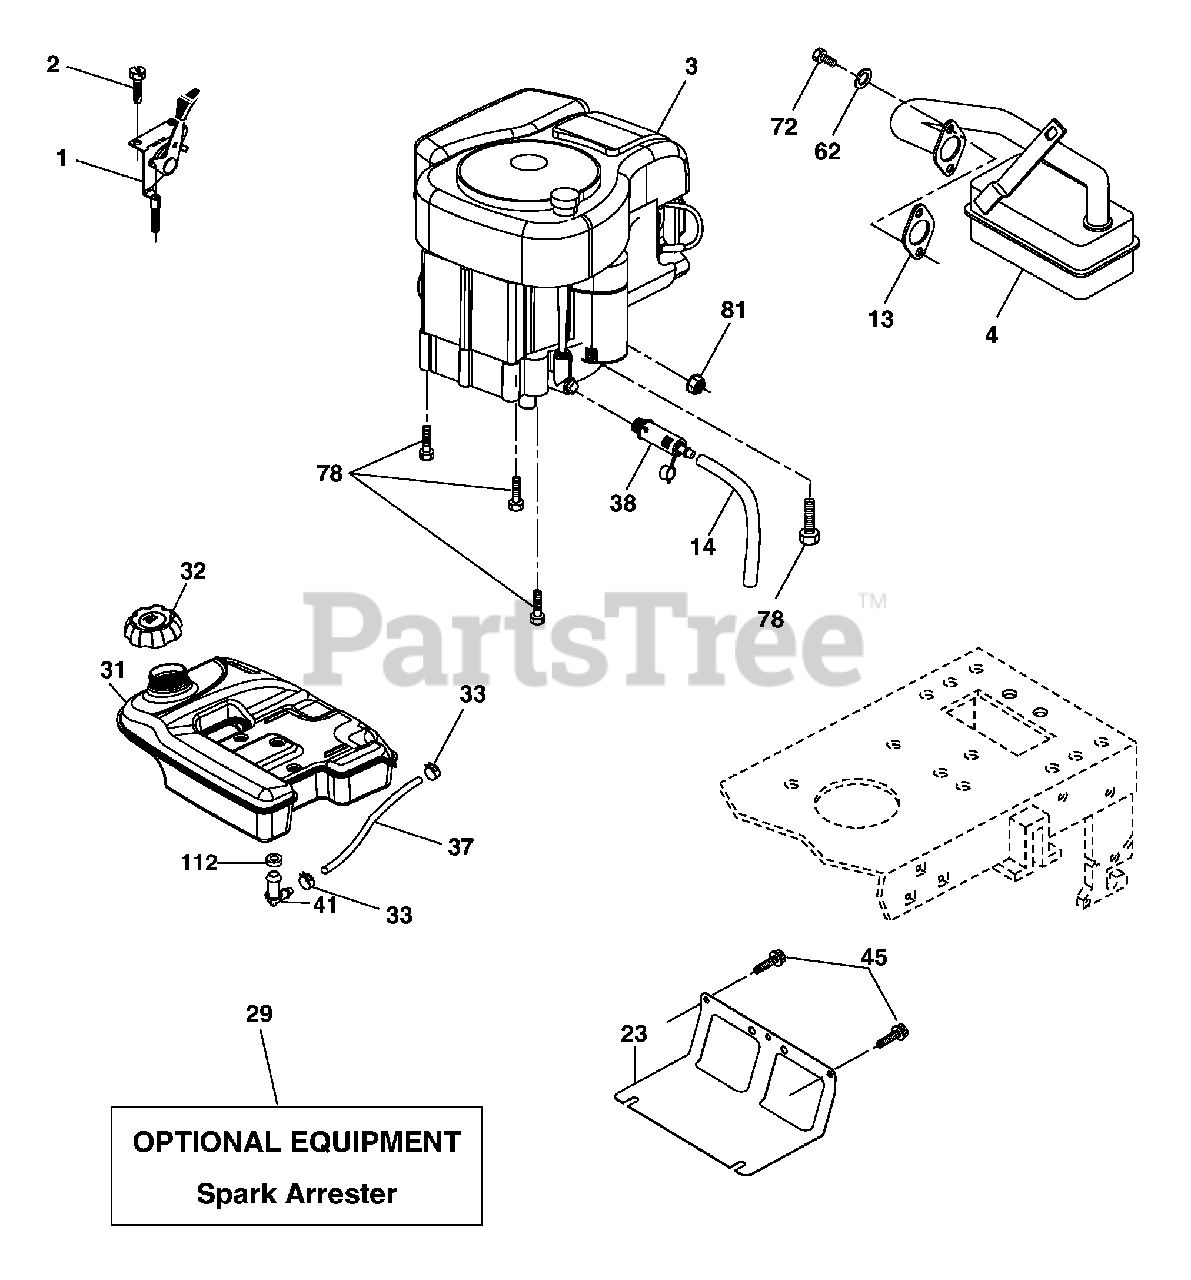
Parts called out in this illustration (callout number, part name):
1	Control, Throttle/Choke
2	Screw 10 x 3/4 Single Lead Hex
4	Muffler
13	Muffler Gasket
14	Tube Oil Drain
23	Shield, Browning/Debris Guard
29	Arrester, Spark
31	Tank, Fuel
32	Cap Gauge, Fuel
33	Clamp, Hose Blk
37	Line, Fuel
38	Plug Drain Oil Easy
41	Stem Tank Fuel
45	Screw Hex Wsh Thdrol 3/8-16 x 3/4
62	Washer Split
72	Screw Hex Hd Cap 5/16-18 x 3/4
78	Screw 3/8-16 x 1-1/4
81	Nut Keps Hex 1/4-20 unc
112	Bushing
